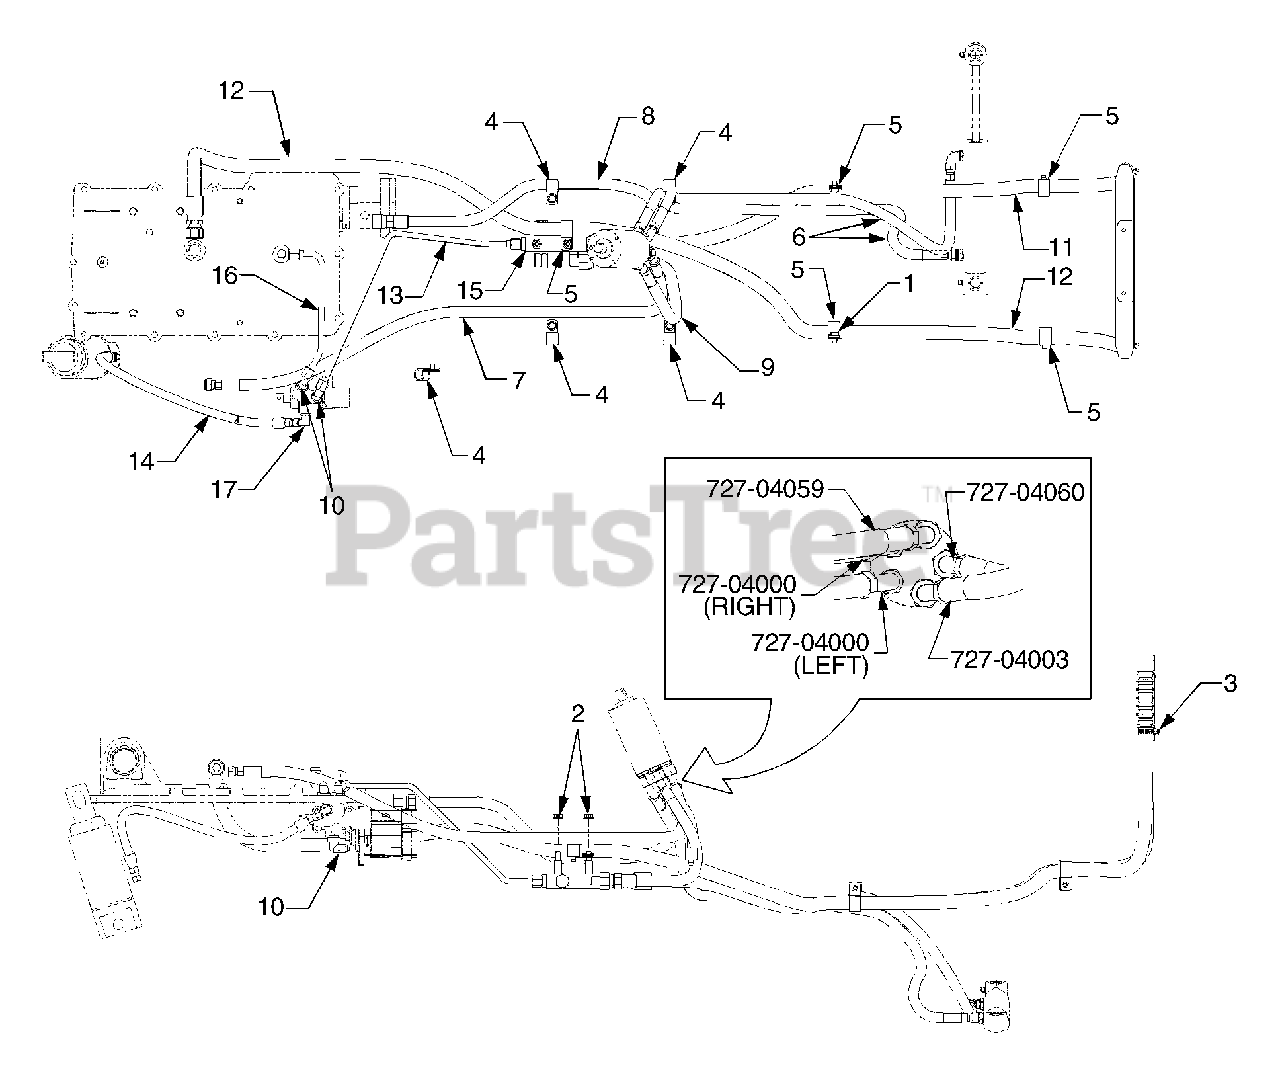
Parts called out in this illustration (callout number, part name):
1	Screw, Hex Wash Hd. Tapp 5/16-18 x .5
2	Nut, Hex Flange Lock, 5/16-18 GR5
3	Clamp, Adjustable Hose
4	Clamp, Hose
5	Clamp, Hose
6	Hose, Steering
7	Hose, Lift Inlet
8	Hose, Steering Pressure
9	Hose, Steering-Tank
10	Fitting, 90 Degree
11	Tube, Oil Cooler Return
12	Hose, Oil Return
13	Tube, Lift Return Line
14	Hose, Lift Cylinder
15	Manifold, Return
16	Tube, Cylinder Return
17	Fitting, 90 Degree
